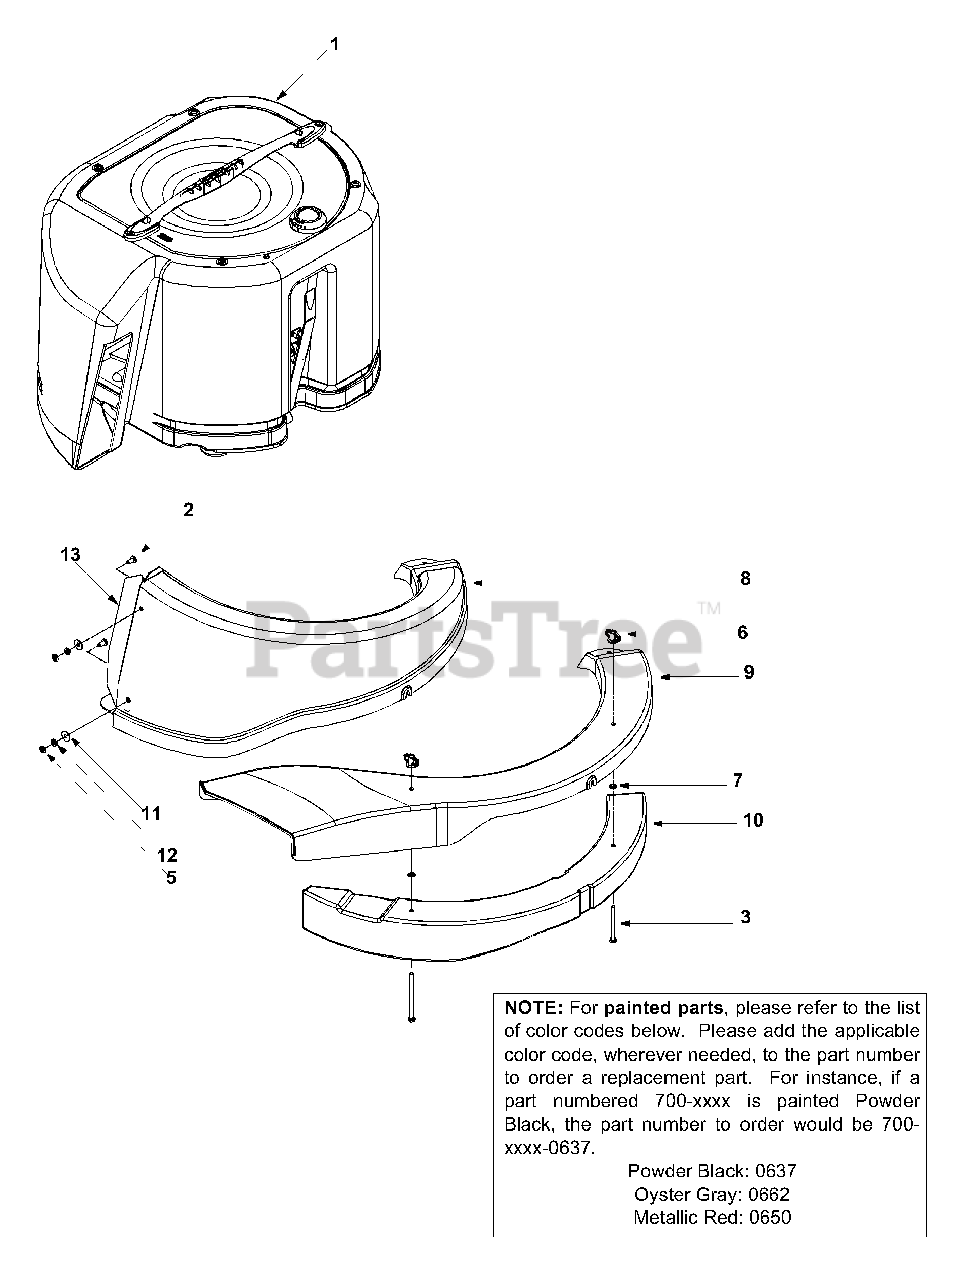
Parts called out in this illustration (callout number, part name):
1	Grass Bag Assembly
2	Pan Hd. Machine Screw 1/4-20 x 0.5
3	Hex Screw 1/4-20 x 2.75
5	Jam Nut
6	Wing Nut
7	Push Nut
8	Chute: Bagger
9	Discharge Chute: Side-Discharge
10	Mulching Plug
12	Lock Washer
